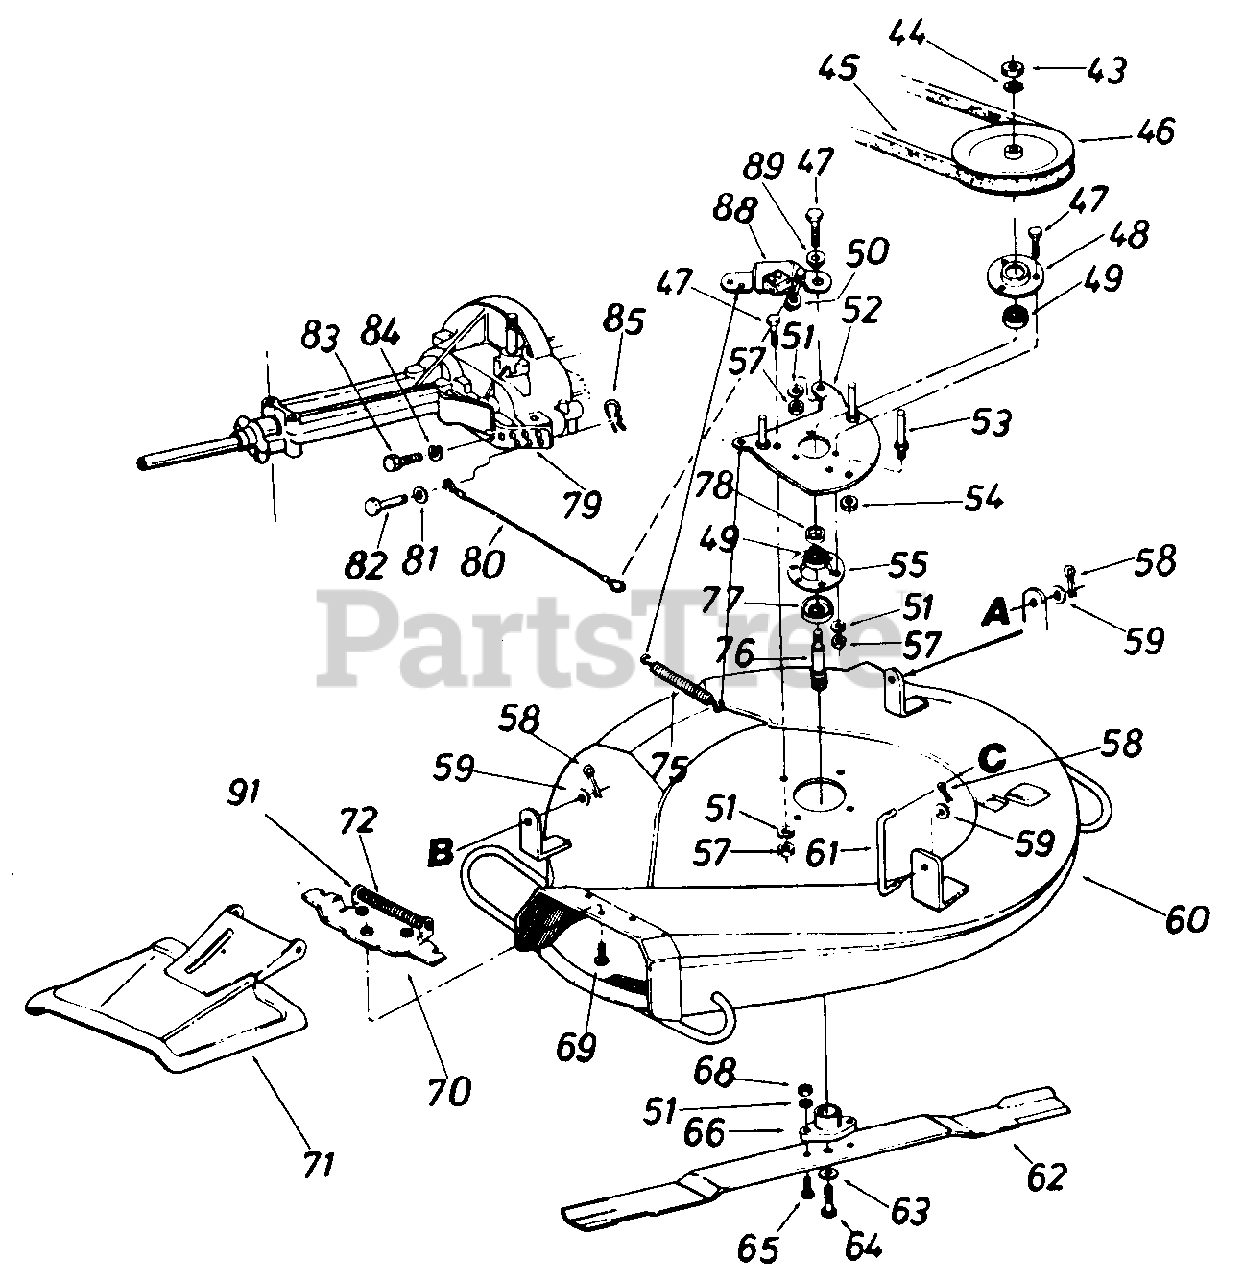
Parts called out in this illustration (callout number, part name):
43	NUT-HEX JAM 5/8-18
44	WASHER-BELL
45	BELT-V 1/2 X 52
46	PULLEY-1/2 V
47	SCREW-HEX 5/16-18 X .75
48	HOUSING-BRG
49	BEARING-BALL
51	WASHER-LOCK-5/16
52	PLATE-MTG-SPINDLE
53	STUD-3/8-16 X 3.0 LG
54	NUT-HEX JAM 3/8-18
55	HOUSING-BRG
57	NUT-HEX 5/16-18
58	PIN-INTERN COT
59	WASHER-FL-.385 ID X .87 OD X .06
60	DECK ASSEMBLY-26IN
61	LINK-DECK
62	BLADE-26IN
63	WASHER-BELL .390 ID X 1.375 X .062
64	BOLT-3/8 NF X 1"GR5
65	SCREW-HEX SPECIAL 5/16-24X1.0
66	ADAPTER-BLADE
68	NUT-5/16-24
69	SCREW-HEX WASH SF TAPP
70	ADAPTER
71	COVER-CHUTE-COMP
72	SPRING-TORSION
75	SPRING-EXTENSION
76	SPINDLE-BLADE
77	SHIELD-BRG
79	GUARD-BELT-LOWER
80	CABLE ASSY-BRAKE
81	WASHER-FL-.281 ID X .50 OD X .063
82	PIN-CLEVIS-1/4X1/2
83	SCREW-HEX 1/4-20 C .62
84	LOCK WASHER 1/4 DIA
85	PIN-INTERN COT-5/16 DIA
88	BRACKET ASSY
89	SPACER-SHLD
91	PIN-HINGE
